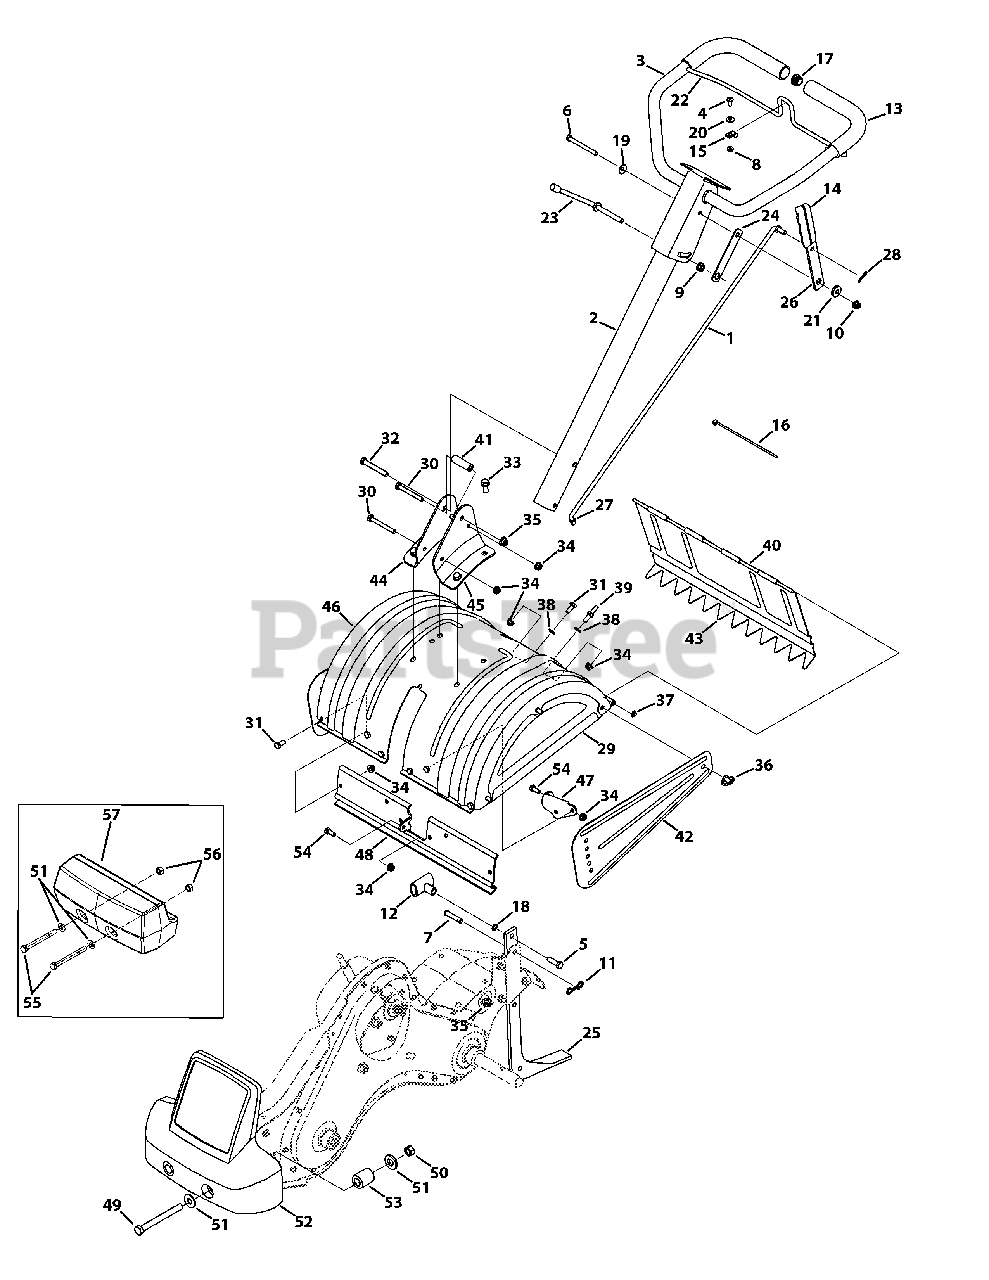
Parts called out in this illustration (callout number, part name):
1	Shaft Rod
2	Lower Handle Tube Assembly
3	Upper Handle Assembly
4	Screw, 1/4-20 x 0625
5	Hex Head Screw, 3/8-16:125
6	Hex Head Screw, 5/16-18 x 325
7	Clevis Pin, 375 X 175
8	Nylon Hex Lock Nut, 1/4-20
9	Flangelock Nut, 3/8-24
10	Hex Flange Top L-Nut, 5/16-18
11	Internal Cotter Pin
12	Small Tee Knob
13	Foam Grip, 970 x 110
14	Grip, 1875 x 100
15	Battery Clamp, 5/16
16	Cable Tie, 85 LG
17	End Plug
18	Washer, Flat, 385 x 620 x 033
19	Washer, Bell, 340 x 872 x 060
20	Washer, Flat, 260 x 720 x 060
21	Spacer, Shoulder, 50 x 190 x 360 LG
22	Clutch Bail
23	Handle Adjustment Crank
24	Hex Nut Retainer Bracket
25	Tiller Depth Control
26	Shaft Rod Lever
27	Washer, Rubber, 33 ID x 87 OD x 125
28	Cotter Pin, 072 x 112 LG
29	End Cover Assembly
30	Hex Head Screw, 5/16-18 x 275
31	Hex Head Screw, 5/16-18 x 75
32	Hex Head Screw, 3/8-16 x 275
33	Hex Head Flange, 3/8-16 x 875
34	Flangelock Nut, 5/16-18
35	Flangelock Nut, 3/8-16
36	Wing Nut, 5/16-18 W/ Bell Washer
37	Speed Nut Cap, 1/4 ROD
38	Washer, Flat, 344 x 62 x 033
39	Screw, Hex, 5/16-18 x 75
40	Tiller Flap Rod
41	Spacer, 322 x 625 x 200
42	Side Shield
43	Rear Tine Shield
44	RH Handle Mount Bracket
45	LH Handle Mount Bracket
46	Tine Shield
47	FRT Tine Shield Bracket
48	FRT Tine Shield Spacer Bracket
49	Hex Head Screw, 1/2-13 x 550
50	Hex Nut, 1/2-20
51	Washer, 1/2 x 125 x 10
52	Counterweight
53	Hub, 636 ID x 100 OD x 94
54	Hex Head Screw, 5/16-18 x 100
55	Hex Bolt, 1/2-13 x 50
56	Flange Lock Nut, 1/2-13
57	Counterweight, 40 lbs
